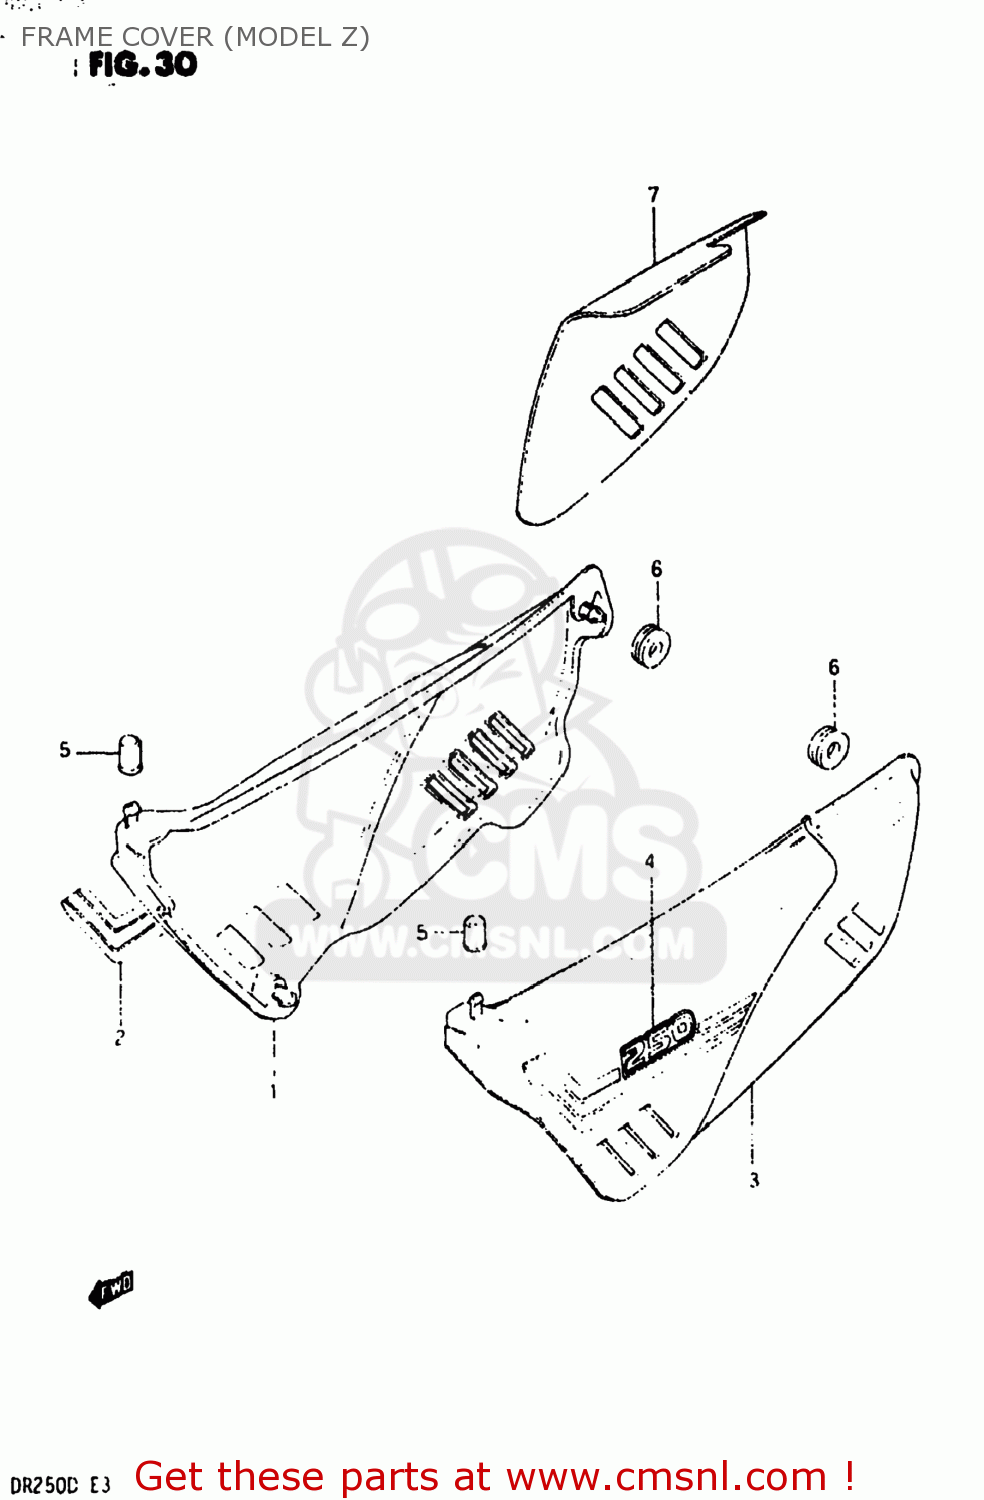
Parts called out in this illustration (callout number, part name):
1	COVER,FRAME,RIGHT
2	TAPE,FRAME COVER,RIGHT
3	COVER,FRAME,LEFT
4	TAPE,FRAME COVER,LEFT
5	CUSHION
6	CUSHION
7	HEAT SHIELD,FRAME COVER
